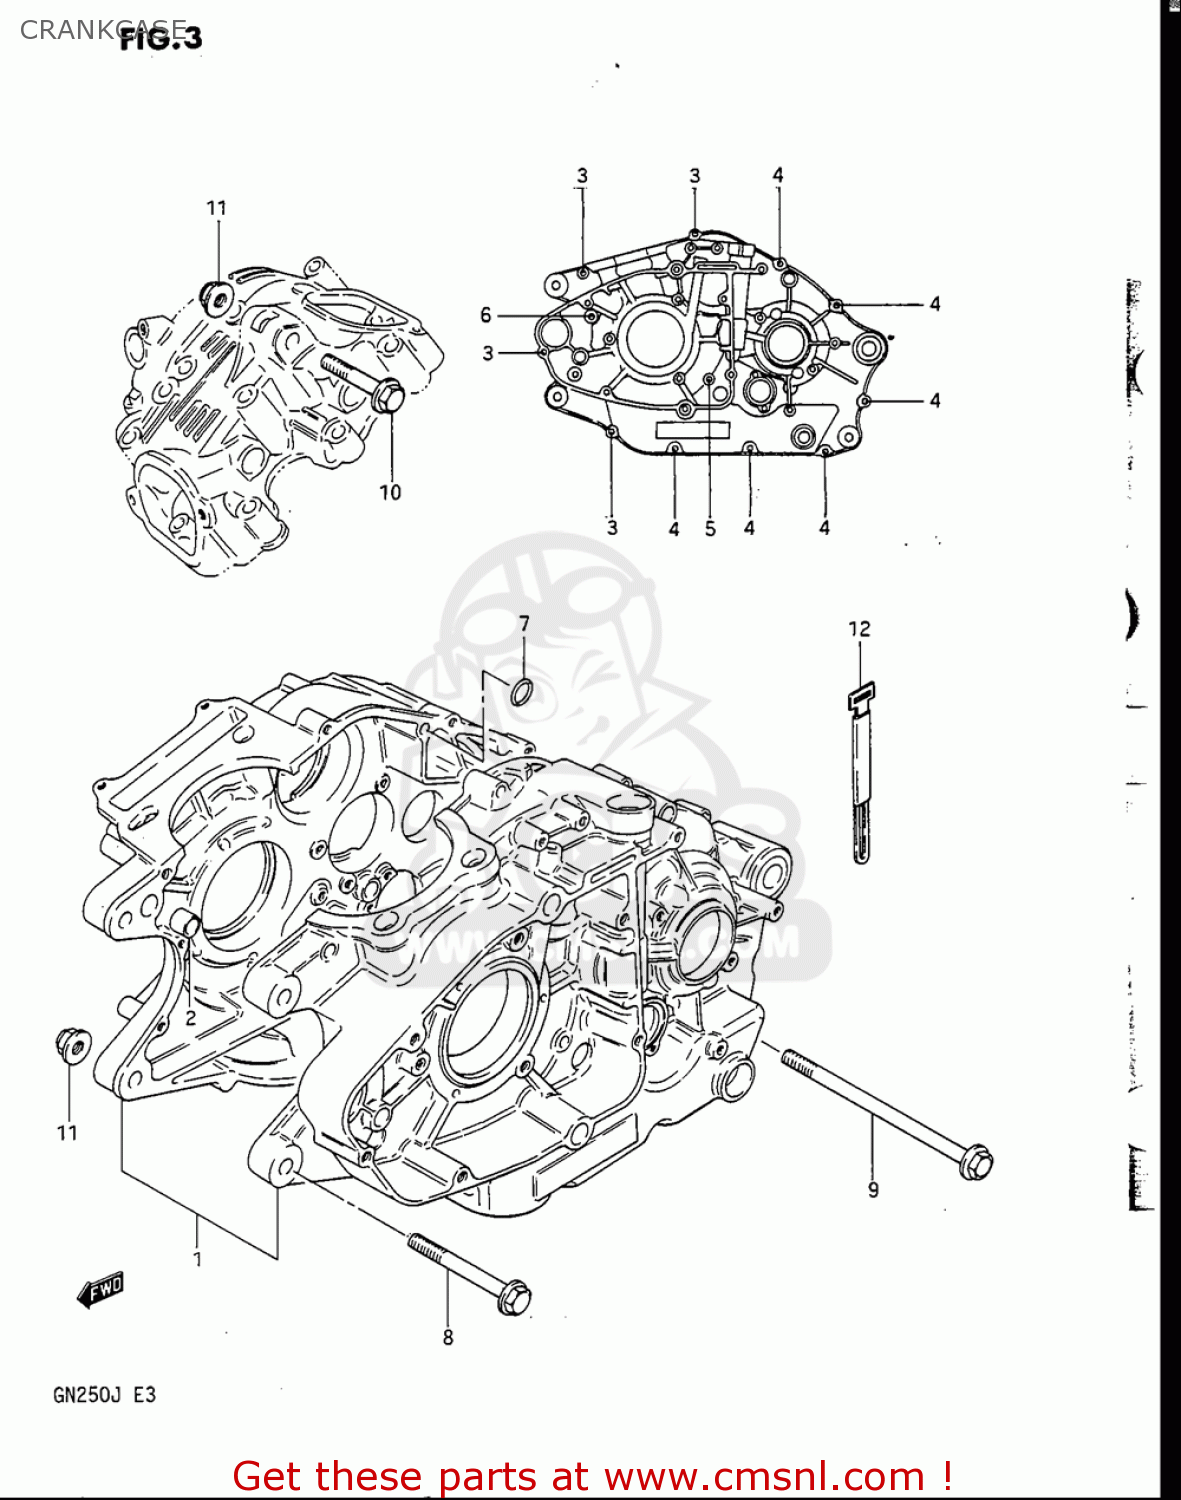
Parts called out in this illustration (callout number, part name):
1	CRANKCASE SET
2	PIN
3	BOLT
4	BOLT
5	BOLT
6	BOLT
7	O RING(D:1.9,ID:8.6)
8	BOLT(8X67)
9	BOLT(8X100)
10	BOLT(8X50)
11	NUT
